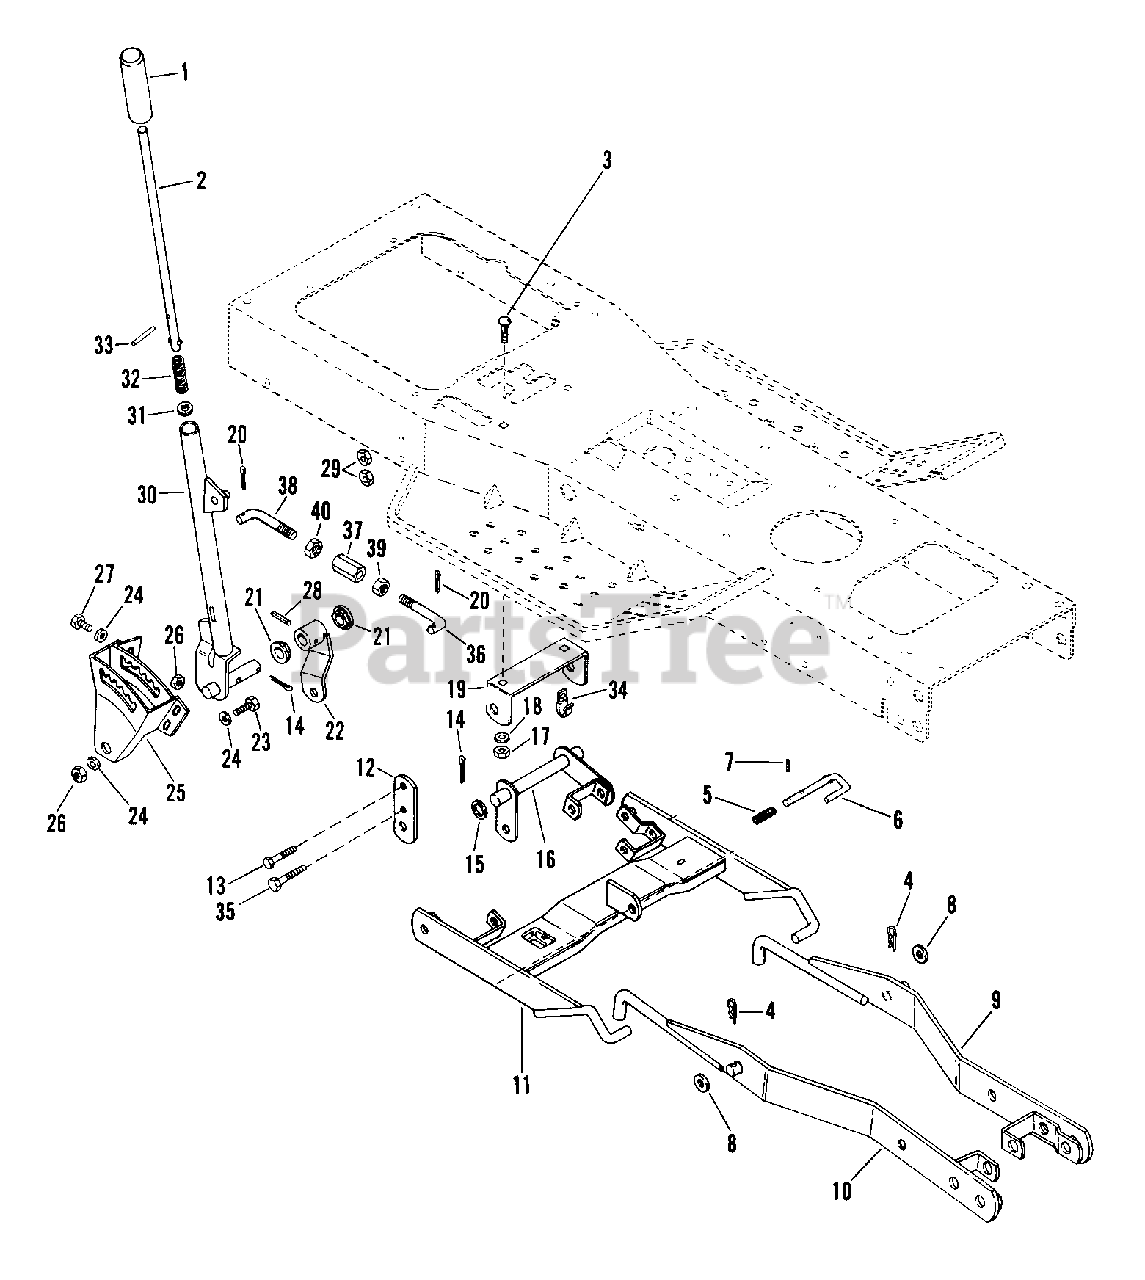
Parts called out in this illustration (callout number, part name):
2	PLUNGER ROD
3	BLT-RDHDSQNK .38-16X.75 SHT PL
4	PIN-HAIR INT .08X.38X1.42 YWZC
5	SPRG, COMP .058X.65X2.13 WLD15
6	LATCH PIN
7	PIN-ROLL .125X.75
8	WSHR-FL-STL .531X1.062X.095 PL
9	LIFT ARM LH
10	LIFT ARM RH
11	REAR HANGER
12	HANGER BRACKET
13	BLT-HEX .38-16X.75 PL GR5
14	PIN-COTR .12X1.50 PL
15	WSHR-FL-STL .754X1.125X.062 PL
16	CENTER LIFT LEVER
17	NUT-HEX .375-16
18	WSHR-LK .375X.094 MED PL
19	CENTER LIFT BRACKET
20	PIN-COTR .12X1.0 PL
21	FLANGE BUSHING
22	LIFT ARM
23	BLT-HEX .31-18X1.25 PL GR5
24	WSHR-FL-STL .323X.625X.062 PL
25	LIFT QUADRANT
26	NUT-LK-TOP .312-18 GR C PL
27	BLT-HEX .31-18X.75 PL GR5
28	PIN-GRV .250X1.25 TP A
29	NUT-LK TOP .375-16 GR C YWZC
30	LIFT HANDLE
31	WSHR-FL-STL .458X.750X.06 PL
32	SG-COMP .048X.59X2.06 WLD9
33	PIN-ROLL .250X1.75
34	J-CLAMP
35	BLT-HEX .38-16X1.00 PL GR5
36	LIFT LINK RH
37	COUPLING NUT .50-13 X 1.50
38	LIFT LINK LH
39	NUT-JAM .50-13 PL
40	NUT-JAM .50-13 LH THD PL
